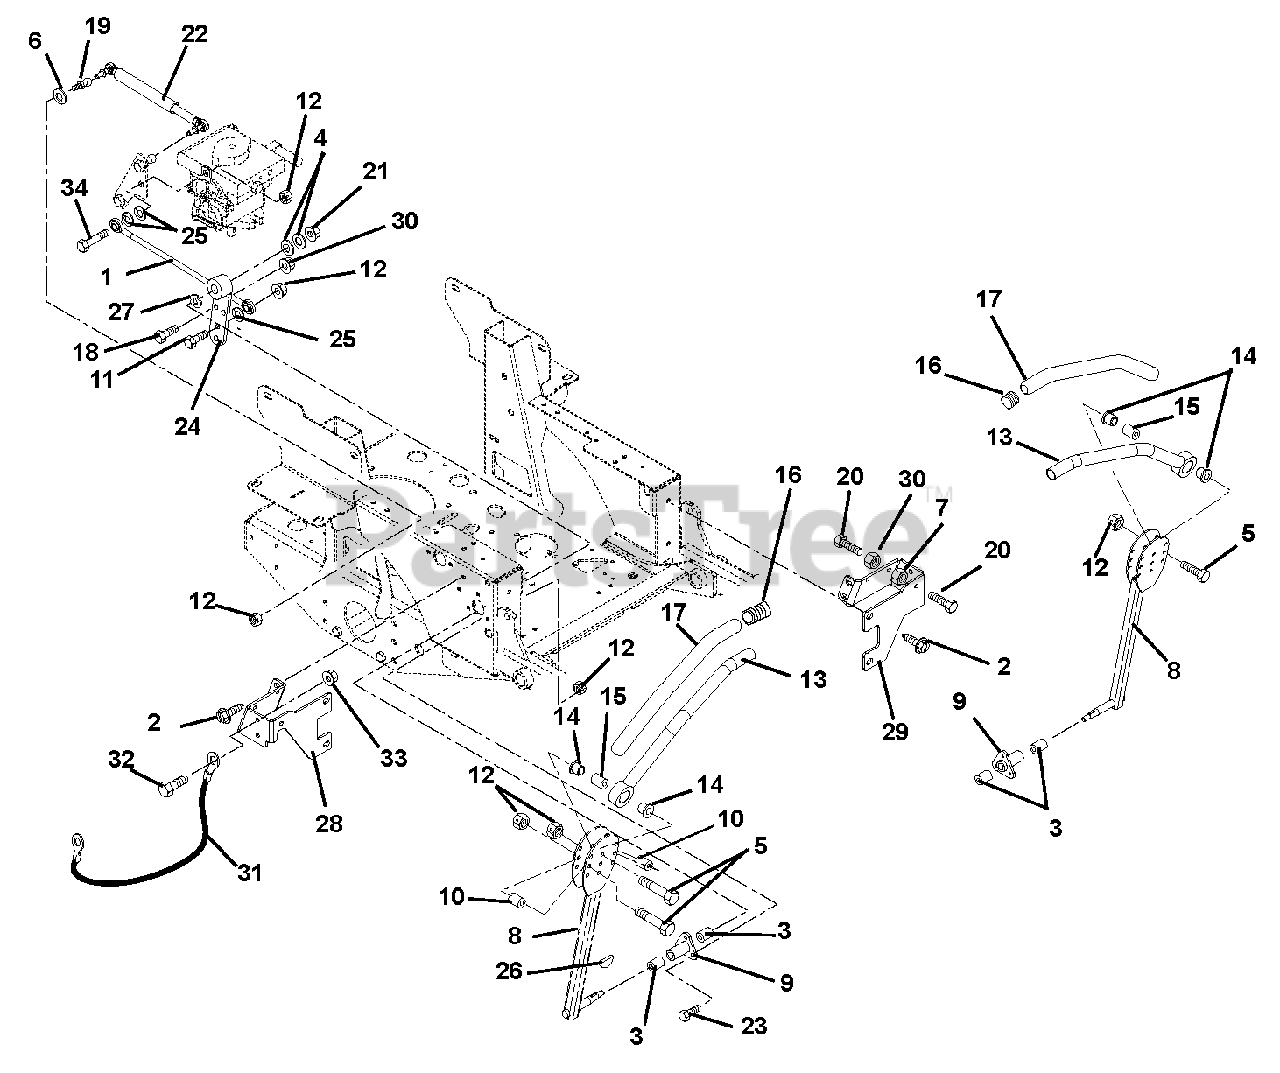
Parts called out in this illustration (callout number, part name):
1	Assembly, Steering Rod
2	Screw, Tapping .38-16 x .75 Hex Washer Head
3	Bushing .625 x .75 x .50
4	Washer, Flat Steel .406 x .812 x .065
5	Bolt, Hex .31-18 x 1.75 Grade 5
6	Washer, Flat Steel .38 x .875 x .083
7	Nut, Hex Jam .375-16
8	Control Arm
9	Housing, Bushing
10	Eccentric
11	Bolt, Hex .31-18 x 1.25 Grade 5
12	Nut, Nyloc Flange .375-16
13	Handle Weldment Left-Hand
13	Handle Weldment Right-Hand
14	Bushing, Flange Nylon .762 x 1.48 x .44
16	Caplug, Handlebar
17	Grip, Handlebar
18	Bolt, Hex .375-16 x 1.75
19	Stud, Ball
20	Bolt, Hex .38-16 x 1.25 Grade 5
21	Nut, Nyloc Flange 3/8-16
23	Bolt, Hex .31-18 x 1.00 Grade 5
24	Weldment, Pivot Arm
25	Washer, Locking .31 x .078 Regular
26	Key, Woodruff .13 x .63
27	Wave Washer
28	Stop, Steering-Right Hand
29	Stop, Steering-Left Hand
30	Nut, Locking Jam Center .375-16
31	Cable, Hood
32	Bolt-Hex .25-20 x .75 Grade 5
33	Nut, Nyloc Flange .25-20
34	Bolt, Hex .31-18 x 1.50 Grade 5
